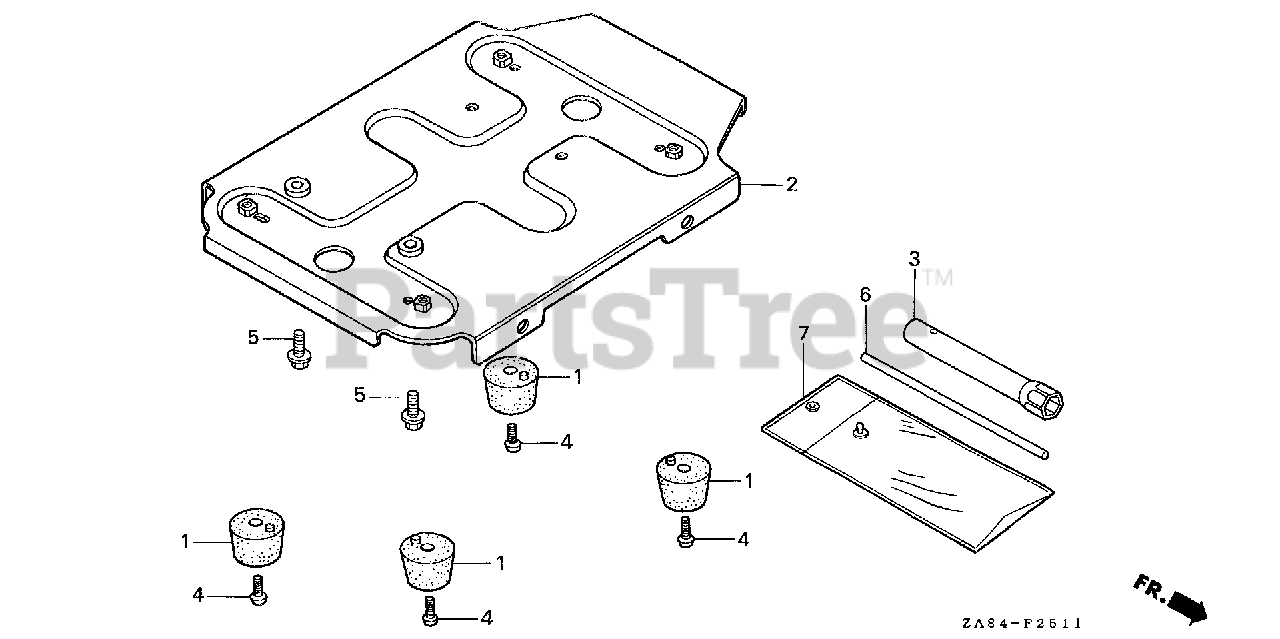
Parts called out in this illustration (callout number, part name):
1	RUBBER (LOWER)
2	PLATE, BASE
3	WRENCH, SPARK PLUG (NOT AVAILABLE)
4	SCREW, PAN (6X10)
5	BOLT, FLANGE (8X18)
6	BAR A, HANDLE
